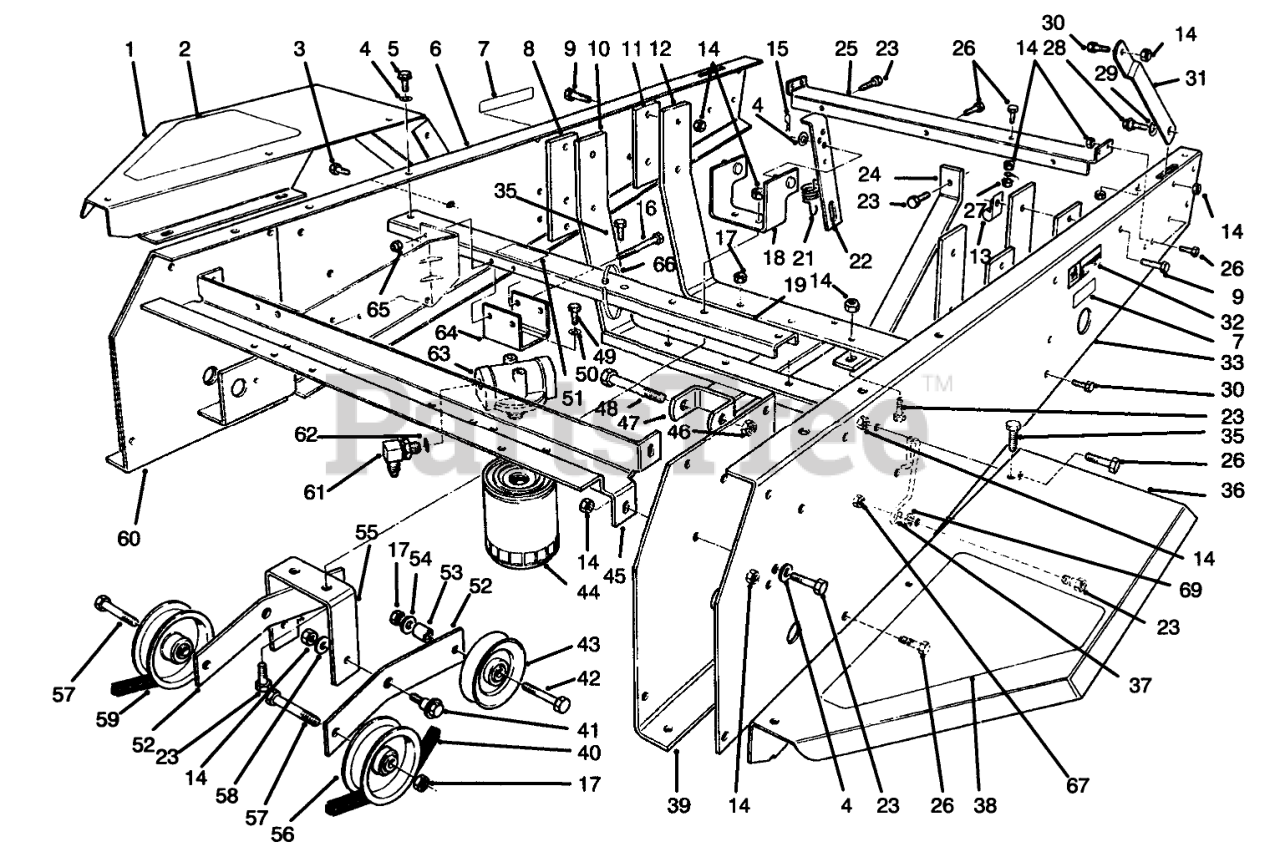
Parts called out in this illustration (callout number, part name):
1	Fender R.H
2	RH FENDER PAD
3	SCREW-HHF
4	WASHER-PLAIN
5	SCREW-HWHTF
6	Channel-Side R.H.
7	DECAL-WARNING
8	FRONT ENG PLATE
9	SCREW-HH
10	Mount-Engine
11	REAR ENG PLATE
12	Mount-Engine
14	NUT-LOCK, NI
15	PIN-COTTER
16	SCREW-HH
17	NUT-LOCK, NI
18	Anchor-Spring
19	MIDDLE CHANNEL WA B
20	SCREW-HH
21	IDLER SPRING
22	IDLER ANCHOR LINK
23	SCREW-HH
24	Bar-Tension
25	Support-Shield
26	SCREW-HH
27	NUT-KEPS
28	SCREW-SHOULDER
29	WASHER-SPRING
30	SCREW-HH
31	Stop-Hood Lower
32	DECAL-HOT
33	Channel-Side LH.
35	SCREW-HHFTF
36	Fender L.H.
37	BELT GUIDE
38	LH FENDER PAD
39	Axle Stand-LH.
40	V-BELT, JACKSHAFT
41	SCREW-SHOULDER
42	SCREW-HH
43	PULLEY
44	FILTER-OIL, TRANSMISSION
45	Channel-Front
46	NUT-LOCK
47	Mount-Cylinder
48	SCREW-HH
49	SCREW-HH
50	WASHER-LOCK
51	DECAL-OIL
52	IDLER LEVER
53	SPACER-WEIGHT
54	WASHER-FLAT
55	IDLER MT BRKT
56	PULLEY
57	SCREW-HH
58	WASHER
59	V-BELT, TRACTION
60	Axle Stand R.H.
61	FITTING-ELBOW, 90
62	O-RING
63	FILTER HD ASM
64	BRACKET - FILTER HEAD
65	NUT-LOCK, NI
66	TIE-CABLE
67	NUT-HF
69	WASHER-LOCK
